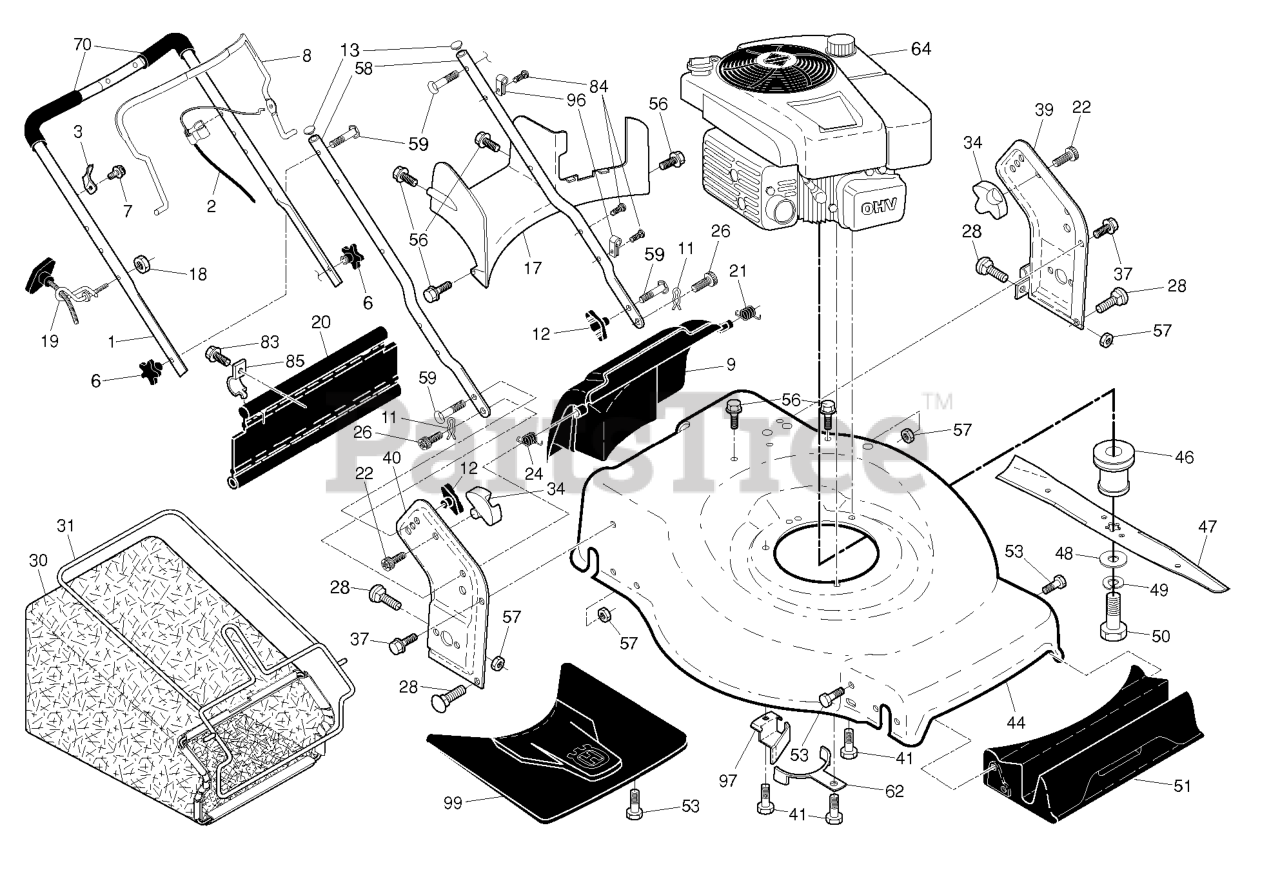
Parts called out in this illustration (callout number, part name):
1	HANDLE.ASM.UPPER.W/GRIP
2	CABLE.MZR.RGD.22.B&S/HON.ERGO
3	BRACKET.UPSTOP.RT
6	KNOB.HANDLE.PLASTIC.STAR.BLACK
8	BAIL.CONTROL.MZR.BS.ORANGE
9	DOOR.REAR.ASM.22+.HUSQ.FG/RGD
11	COTTER.HAIRPIN.DOOR/HANDLE.PIV
12	KNOB, DEFLECTOR
13	PLUG.PLASTIC.7/8".14-20.GAUGE
17	RP.BAFFLE.REAR.22+.RGD.PL
18	NUT
19	RB GUIDE.ROPE.STD.BLK.ZIN WSL
20	SKIRT.REAR.22+.RGD.HW
21	SPRING.LH.BLACK
22	SCREW.PAN.HEAD.#10
24	SPRING.RH.GRAY
26	SCREW,DOOR/HANDLE.PIVOT
28	BOLT
30	GBAG.A3610247T.SILV.HUSWT.BLUE
31	RB FRAME.GBAG.22PLUS
34	BRACKET.GRASSBAG.ATTACHING.BLK
37	BOLT.HEX.HD.WASHER.5/16-18X.75
39	BRACKET.ASM.HANDLE.LT
40	RP.BRACKET.ASM.HANDLE.RT.22+.
41	BOLT 3/8-16X1-1/8
44	HOUSING.22+.RWD.WO/PORT.ORANGE
46	ADPTER.BLAD.25M.VS.22PLU.STAR
47	BLADE.22+FUSION.PREM/PREC
48	WASHER,HARDEN
49	LOCKWASHER
50	SCREW, HEX HD 3/8-24 X 1-3/8
51	BAFFLE.FRONT.22PLUS.PLASTIC RP
53	SCREW.HI-LO.5/16 X.75
56	SCREW.HX.13X.750
57	NUT.FLANGE.5/16
58	HANDLE.LOWER.22+BT.2PC.GRY
59	BOLT, HANDLE 5/16-18X1.75
62	BRACKET.ENG/BELTKEEPER
70	GRIP.HANDLE.FOAM.WIDE.(1 SIDE)
83	TAPPING SCREW
84	FASTENER.PUSH.O.250X0.783
85	BRACKET.SKIRT.22+.BZP
96	CLIP.CABLE.BLK
97	BRACKE.BELT.GUIDE.22+
99	COVER.ASM.FRONT.SHROUD.HUSQ.
